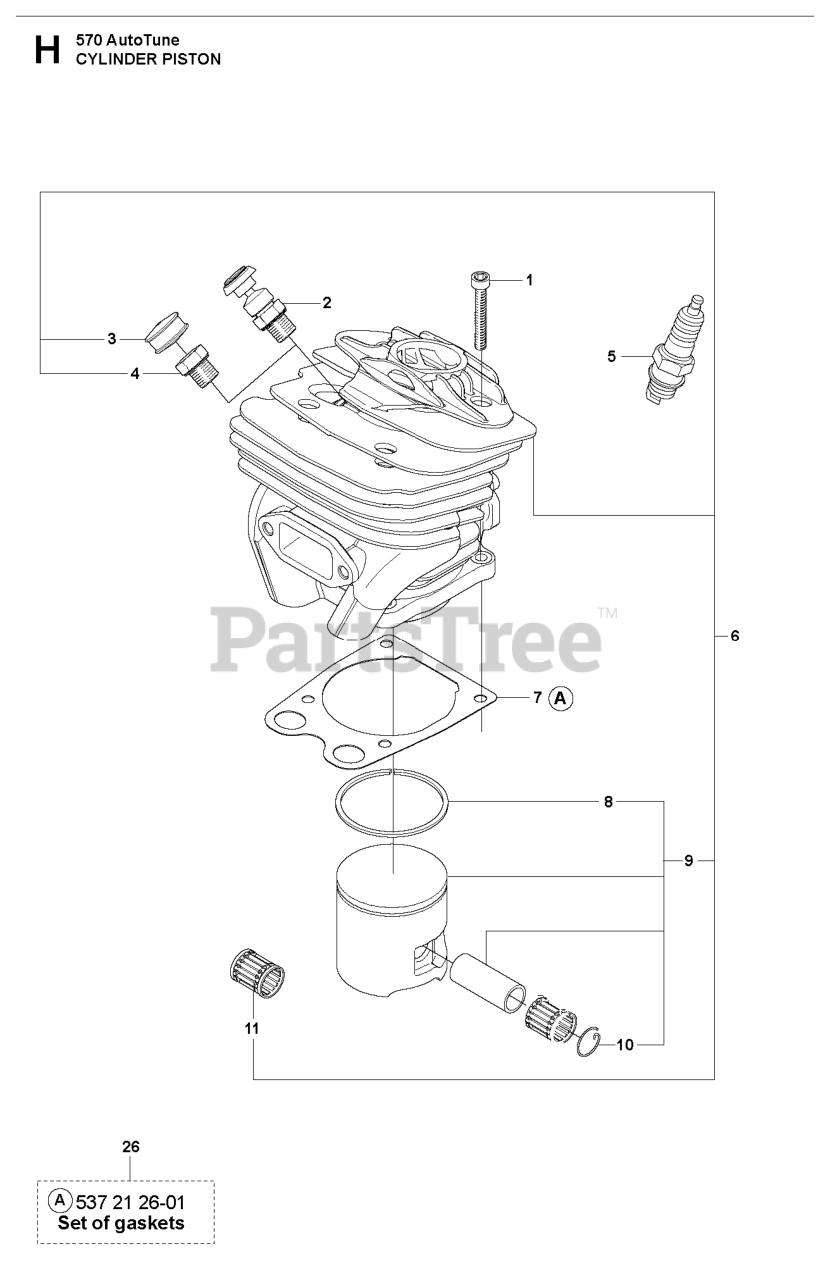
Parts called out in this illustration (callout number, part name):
1	SCREW MC6S 5X25
4	CYLINDER PLUG
5	SPARK PLUG M14X1.25 NGK BPMR7A
8	PISTON RING
9	PISTON 49 MM
10	WRIST PIN CLIP
11	NEEDLE BEARING PISTON PIN 12X1
26	GASKET SET
